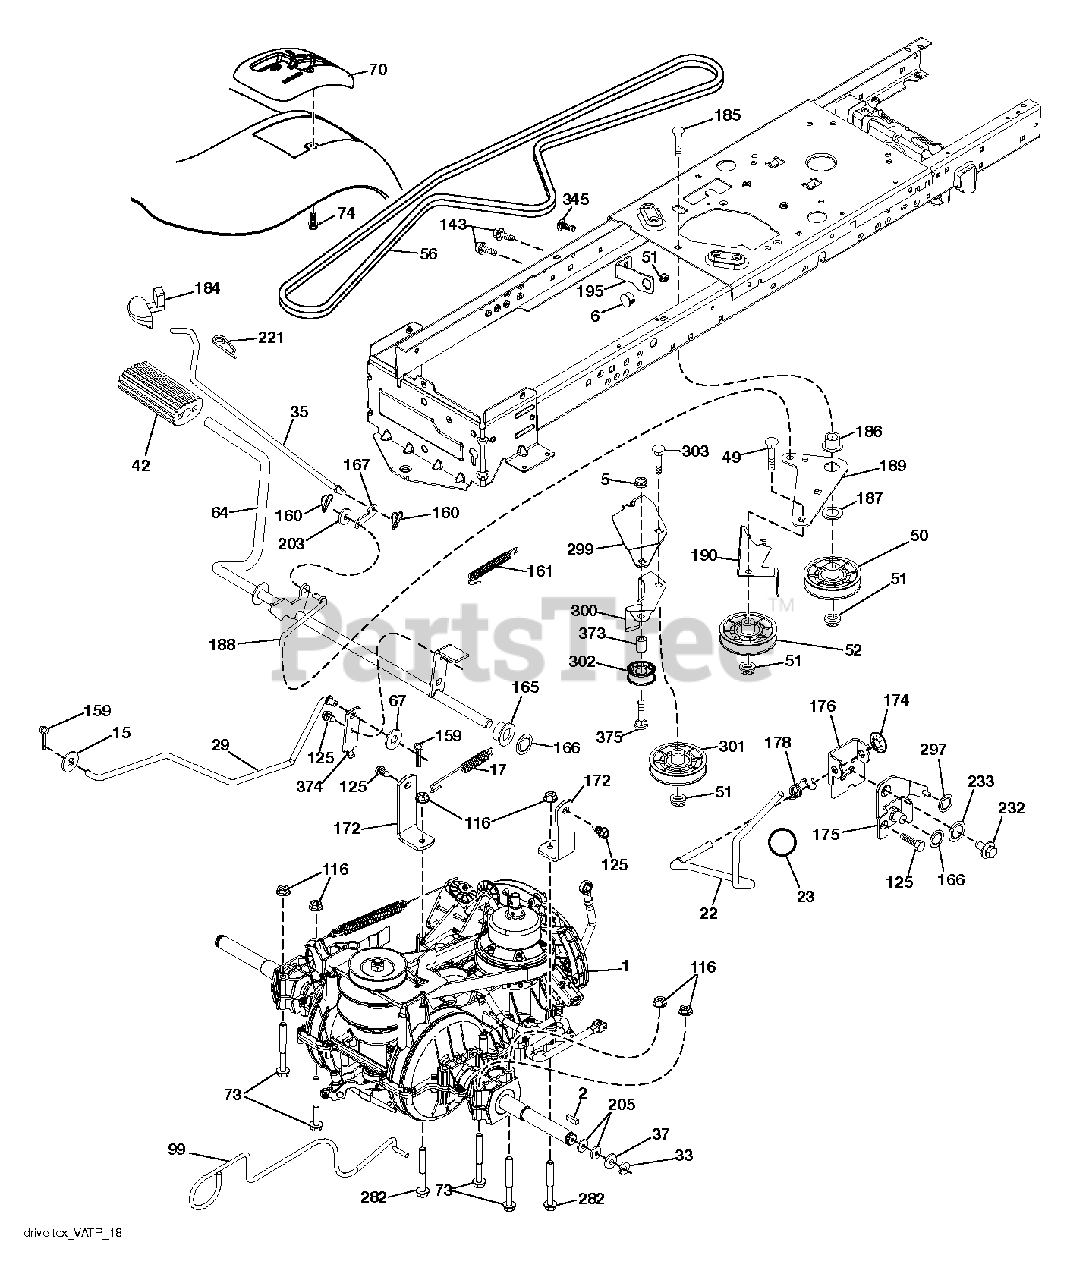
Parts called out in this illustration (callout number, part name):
2	SQUARE KEY
5	LOCKNUT
6	GROMMET T
17	Brake Variator Spring
22	ROD.SHIFT.LT.TEX.VARIATOR
23	KNOB.DELUXE.(PISTOL.GRIP).BLAC
29	RB ROD.BRAKE.VARIATOR.SD2
33	E-RING LT
35	ROD.BRAKE.PARKING.LT.T
37	WASHER.HARDENED
49	BOLT
50	IDLER.FLAT.910.OFFSET
51	NUT LOCK FLG 3/8-16 UNC
52	IDLER.V-GROOVE.910.OFFSET
56	BELT.DRIVE.MOWER.TEX.42"
64	SHAFT SUB ASM PEDAL BRAKE
67	WASHER
70	CONSOLE.AUTO.VARIATOR.BLACK
73	BOLT HEX 5/16-18 GR 5
74	SCREW.HI-LO.CONSOLE
99	ROD.BYPASS.VARIATOR.GEN2
116	NUT LOCK HEX FLANGE 5/16-18
125	SCREW
143	SCREW LT
159	COTTER PIN
160	RETAINER CLIP
161	SPRING, RETURN LT
165	BUSHING.SHAFT.BRAKE.HAND
166	NUT.PUSH.625
167	LATCH.BRAKE.SPRING
174	NUT.PUSH.500.2006
175	SHAFT.ASM.SHIFT.VARIATOR
176	ARM.CLEVIS.ROD.SHIFT
178	SPRING.SHIFT.GT2006
184	HANDLE.PARKING.BRAKE.LTTEX.667
186	SPACER.RETAINER
187	WASHER 12/32X2X10GA
188	LINK.CLUTCH.GROUND.DRIVE
189	BELLCRANK.GROUND.DRIVE.TEX.
190	KEEPER.BELLCRANK.DRIVE
195	BRACKET.BRAKE.BRAKE.VAR.SD
203	WASHER
221	RETAINER.SPRING.CLIP.H
232	BOLT FIN HEX 7/16-14 X 1
233	WASHER SERRATED
282	BOLT HEX FLGHD 5/16-18X3 GR. 5
297	NUT.PUSH.1/4
299	BRACKET.MOUNT.IDLERS
300	KEEPER.IDLERS.REAR.VARIATOR
301	PULLEY.IDLER.V-GROOVE
302	PULLEY.IDLER.FLAT.2"
303	BOLT CARRIAGE
373	SPACER.IDLER
374	ARM.CONTROL.BRAKE
